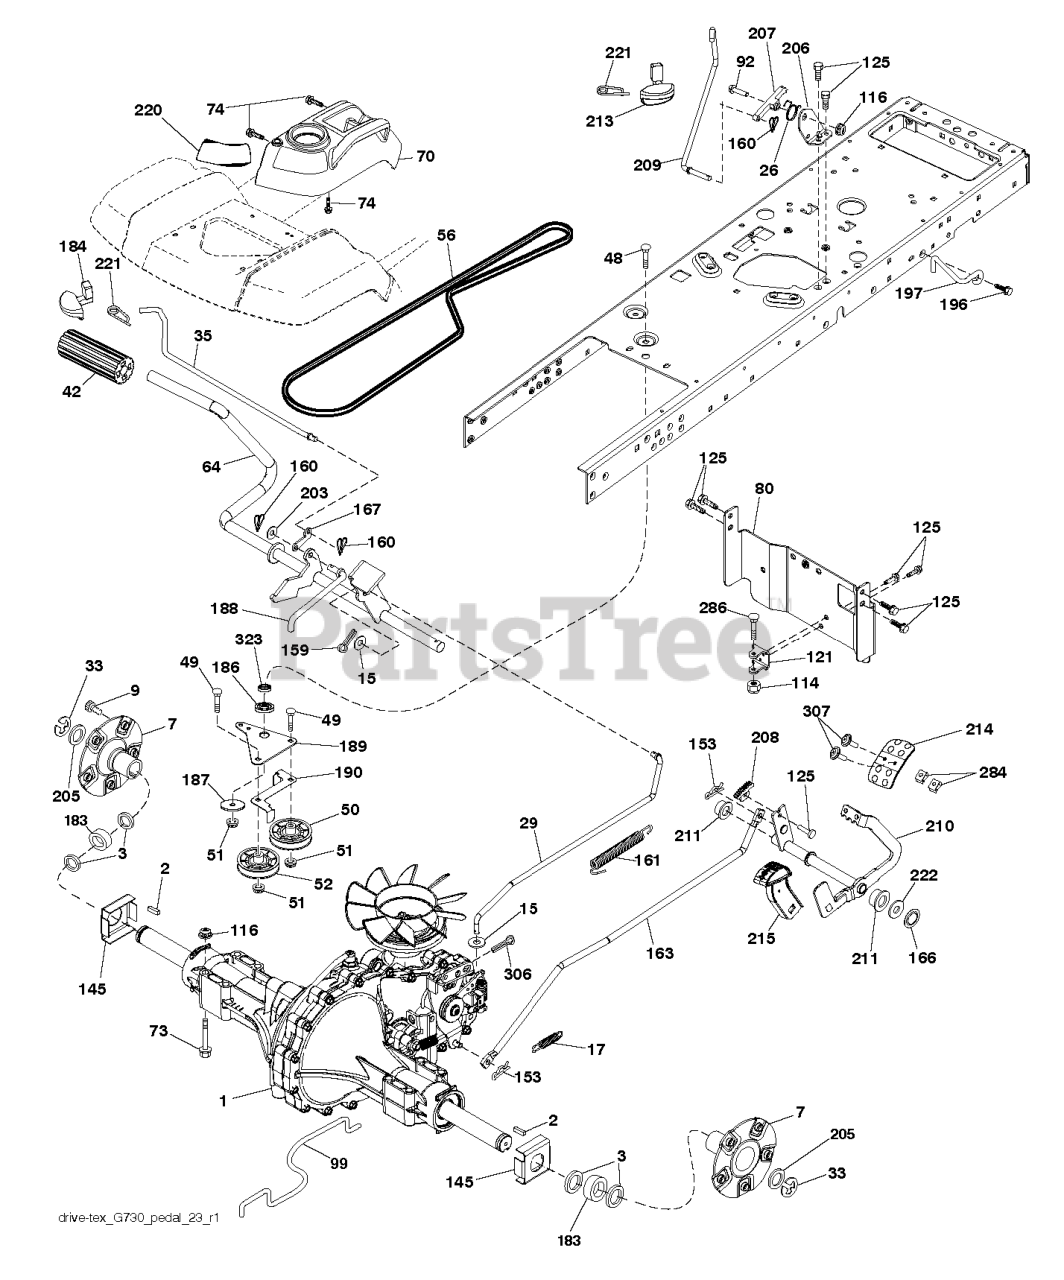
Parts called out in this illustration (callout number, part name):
2	KEY, 1/4 SQ X 1 1/4
7	HUB.PNT.GT.PM.1IN.AXLE.E-DIP
15	WASHER
17	SPRING.BRAKE.HG3000/3500
26	SPRING.RETURN.CRUISE
33	E RING HYT
35	ROD .BRAKE. PARKING. GT. HUSQ.
42	PEDAL COVER T
48	BOLT.3/8-16X1.50
50	IDLER.FLAT.910.OFFSET
51	NUT LOCK FLG 3/8-16 UNC
52	IDLER.V-GROOVE.910.OFFSET
56	V-BELT.GROUND.DRIVE.
64	SHAFT.ASM.PEDAL.BRK.CNTR
70	CONSOLE.ASM.RH.GT.FC.HUSQ
73	BOLT HEX FLGHD 5/16-18X3 GR. 5
74	SCREW.HI-LO.CONSOLE
80	STRAP.TORQUE.YT.G700
92	BOLT
99	SPRING.BYPASS.YT.G700
114	NUT.71038.31-18.HEX.NYLOCK
116	NUT LOCK HEX FLANGE 5/16-18
121	BRACKET STRAP TORQUE
125	SCREW
145	WASHER.AXLE.FLANGE.HG-3000
153	RETAINER M
159	COTTER PIN
160	RETAINER CLIP
161	SPRING, RETURN LT
163	ROD PEDAL CONTROL
166	NUT.PUSH.625
167	LATCH.BRAKE.SPRING
183	SPACER.SPLIT.1.000ID X 1.500
184	HANDLE.PARKING.BRAKE.H (BLK)
186	SPACER.RETAINER
187	WASHER 12/32X2X10GA
188	LINK.CLUTCH.GROUND DRIVE.LONG
189	BELLCRANK.GROUND.DRIVE.TRAPPED
190	KEEPER BELLCRANK ROUND DRIVE
196	SCREW 3/8-16X1
197	CLUTCH.ANTIROTATION.WIREFORM.
203	WASHER
206	BRACKET.MOUNT.CRUISE.LATCH
207	LATCH.CONTROL.CRUISE.TEX
208	GEAR.SECTOR.CONTROL.CR
209	ROD.CONTROL.CRUISE.GT.
210	ROCKER.ASM.PEDAL.CONTR
211	BEARING.NYLON
213	KNOB.CONTROL.CRUSIE.HU
214	PEDAL.FORWARD.HUSQVARNA.DEALER
215	PEDAL.COVER.REVERSE.CRD.X428BK
220	REFLECTOR.RH.TEX GT
221	RETAINER.SPRING.CLIP.H
222	WASHER 21/32 X 1-1/4 X 10 GA.
284	NUT.U-CHNL.1/4-20.550DP.350PNL
286	BOLT.5/16-18X2.5
306	PIN COTTER
307	SCREW.MACHINE.CR.1/4-20
323	SLEEVE.BELLCRANK
